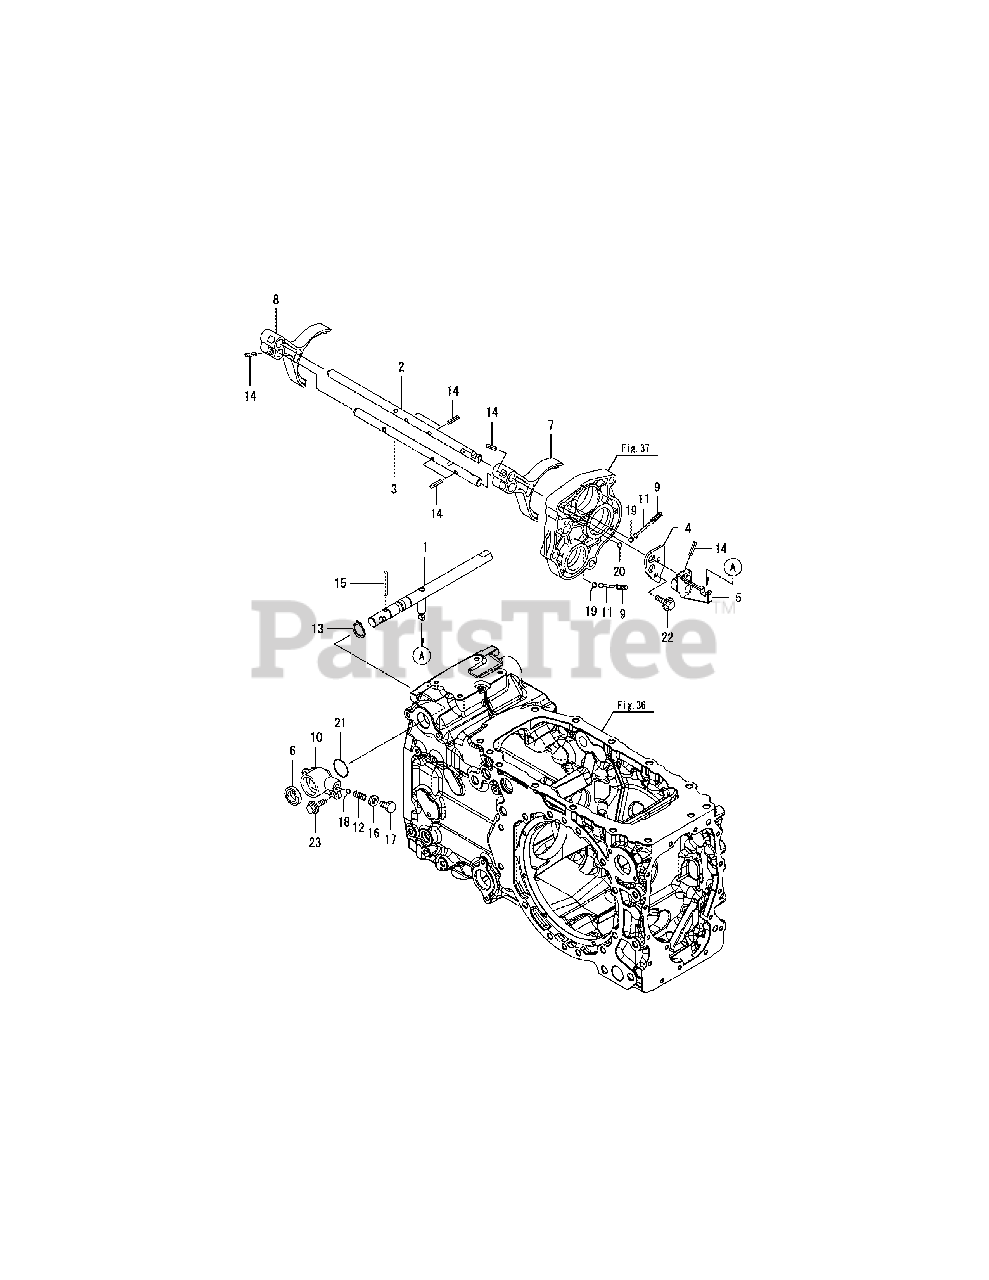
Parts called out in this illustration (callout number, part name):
1	ARM, MAIN SHIFT
2	SHAFT, FORK 3-4
3	SHAFT, FORK 1-2
4	PLATE, FORK LOCK
5	SHIFTER, MAIN SHIFT
6	SEAL TC4 203507
7	FORK, MAIN SHIFT 3-4
8	FORK, MAIN SHIFT 1-R
10	HOLDER, SHIFT ARM
11	PIN 4X35,FLAT HEAD.
14	SPRING PIN 6X25
15	SPRING PIN 6X50
16	GASKET 10, ROUND
18	BALL 5/16, STEEL
19	BALL 5/16, STEEL
20	BALL 5/16, STEEL
22	BOLT M 8X 16 PLATED
23	BOLT M 8X 20 PLATED
